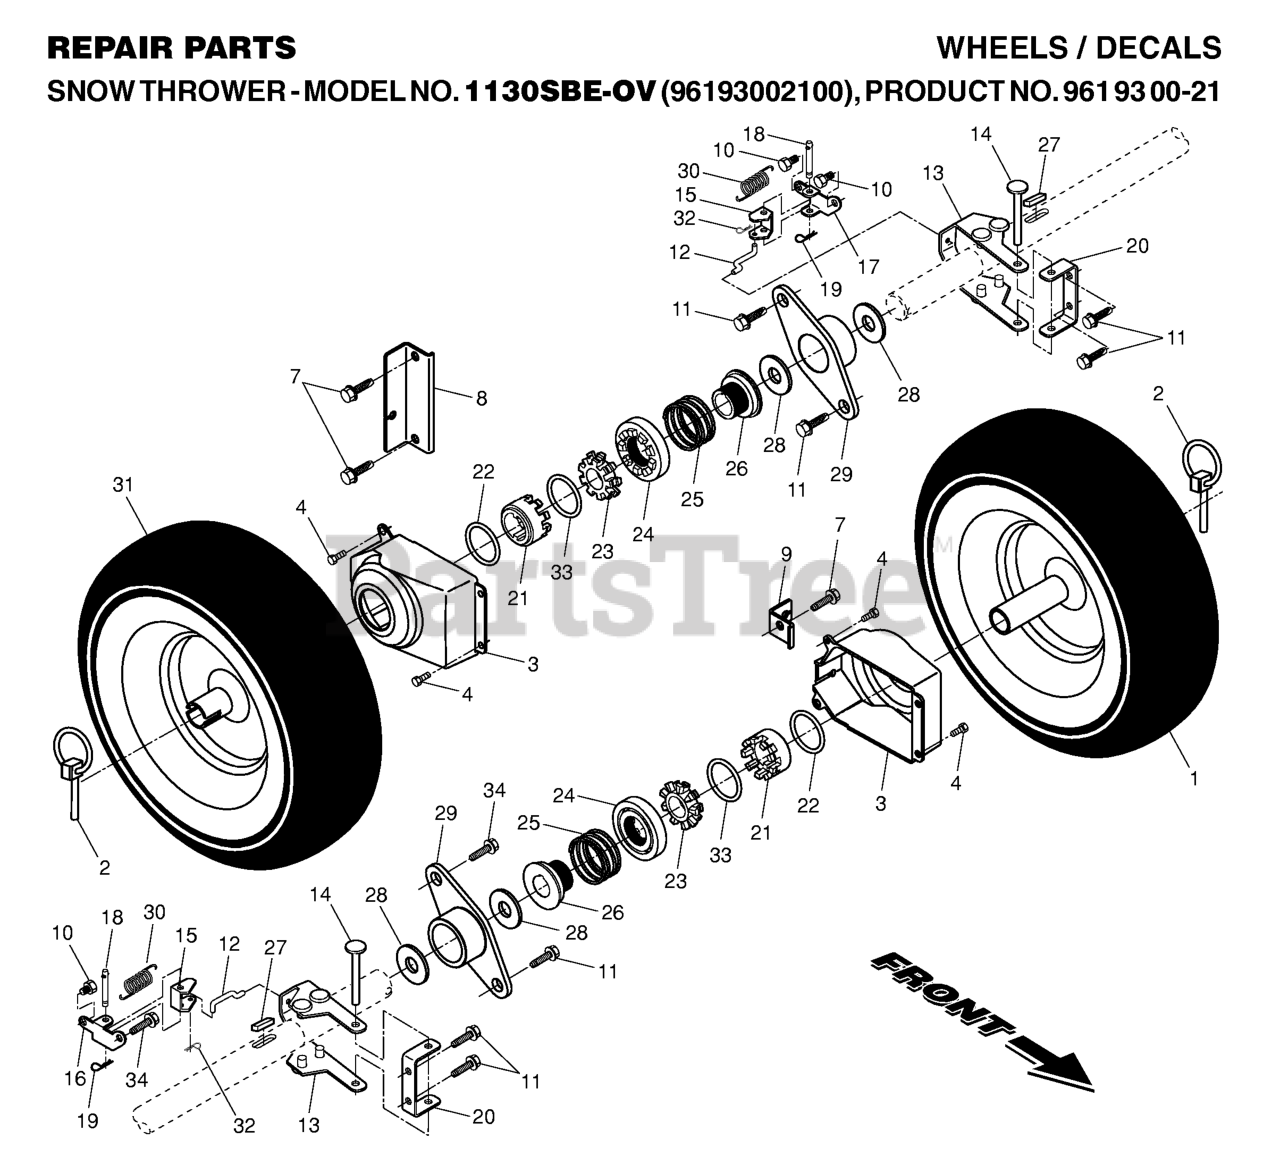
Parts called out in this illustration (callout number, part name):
1	16 X 4.8 LH WHEEL GREY
2	PIN KLIK, 1/4
3	COVER, POWER STEERING
4	SCREW, HEX HEAD, TAPPING
7	SCREW 3/8-16X1
8	BRACKET, STEERING CABLE RH
9	BRACKET, STEERING CABLE LH
10	SCREW 1/4X20
11	SCREW, HEX HEAD 5/16-18 X 1/2
12	LINK, STEERING LEVER
13	STEERING YOKE
14	PIN, STEERING LEVER
15	BELLCRANK.STEER
16	BRACKET.STEER.PIVOT.LH.YZ
17	BRKT.STEER.PIVOT.RH
18	PIN, STEERING BELLCRANK
19	RETAINER CLIP PM
20	BRACKET.STEER.PNT.BLACK
21	RP.DRIVER WHEEL
22	RING, WIRE RETAINER
23	LOBE WHEEL
24	RP.SLIDE.CLUTCH
25	SPRING, CLUTCH SLIDE
26	RP.LOBE.AXLE
27	KEY, SQUARE 1/4 X .875
28	WASHER TRUST 1"
29	BEARING, AXLE
30	SPRING LATCH
31	16 X 4.8 RH WHEEL
32	RETAINER CLIP
